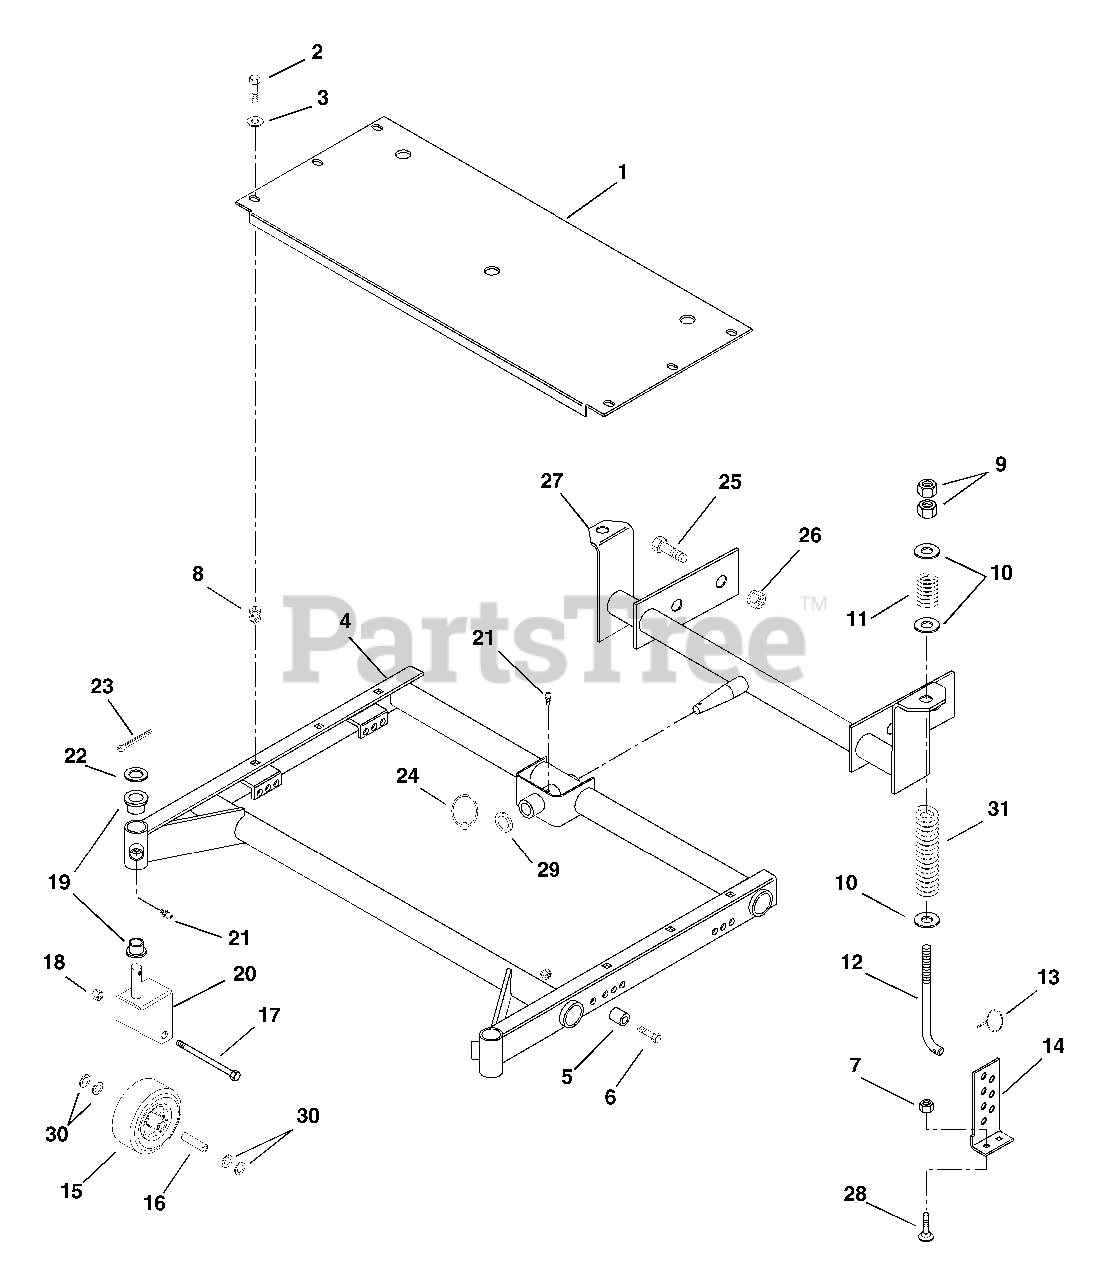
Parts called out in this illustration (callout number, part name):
1	Guard, 50" Mower Belt
2	Screw-Tapping, .25-20 x .50 Hex Slot Head
3	Washer-Flat-Steel .281 x .625 x .065
4	Weldment, Mower Frame
5	Bushing, .391 x .626 x .670
6	Bolt-Hex .38-16 x 1.50 Grade 5
7	Nut-Locking-Nylon .38-16 w/ Insr Grade 2
8	Grommet, Plastic
9	Nut .50-13
10	Washer-Flat-Steel .531 x 1.062 x .095
11	Spring-Compression .125 x 1.00 338 lbs/in
12	Rod, Height Adjuster
13	Pin-Klik 1.000 x .188 x 1.25
14	Bracket, Rear Adjuster Left Hand
14	Bracket, Rear Adjuster Right Hand
15	Wheel, Gauge 9 x 3.50
16	Spacer .532 x .748 x 3.34
17	Bolt-Hex .50-13 x 5.50
18	Nut-Locking-Nylon .50-13 Grade 5
19	Bushing-Flange 1.385 x .75 x 1.75
20	Weldment, Caster Fork
21	Fitting, Lube .25-28 x 2.56
22	Washer-Hardened Thrust 1.002 x 1.552 x .030
23	Pin-Cotter .188 x 1.50
24	Pin-Klik .25 x 1.75
25	Bolt-Hex .62-11 x 1.50
26	Nut-Locking .62-11 Hex w/ Insr
27	Weldment, Mower Frame Mounting
28	Bolt-Round Head Square Neck .38-16 x .75 Grade 1
29	Bearing-Needle-Thrust .752 x 1.24 x .031
30	Washer-Flat-Steel .531 x 1.250 x .100
31	Spring-Compression .095 x .75 x 6.25
